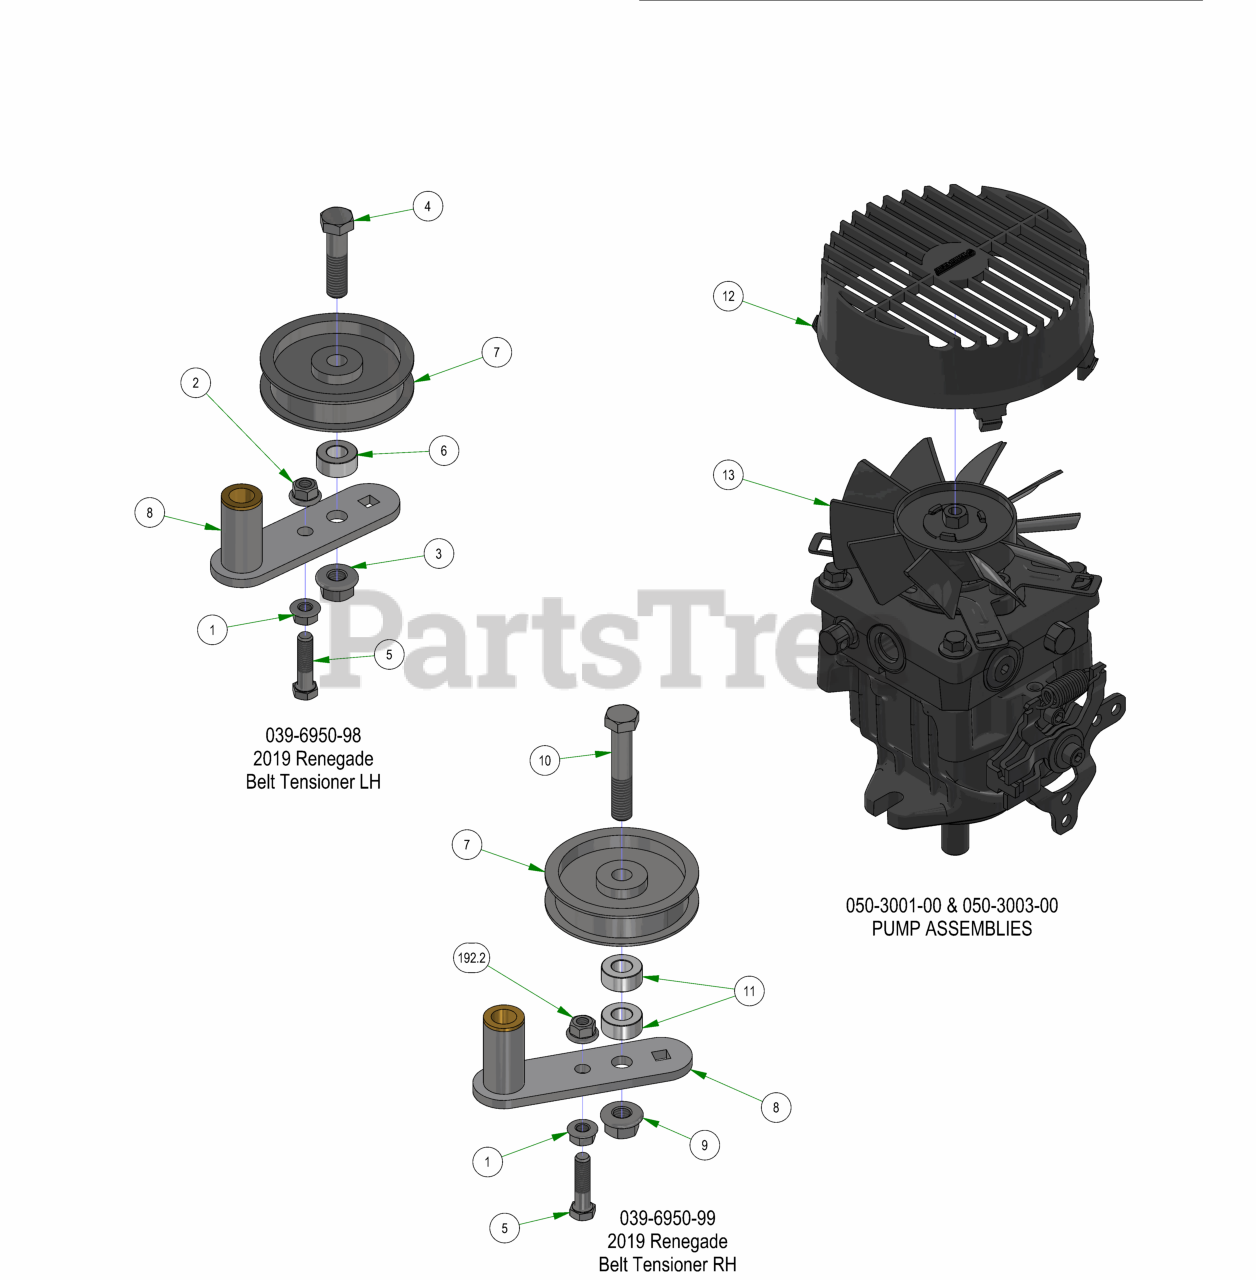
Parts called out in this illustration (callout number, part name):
1	3/8-16 HEX SERRATED FLANGE NUT HARD/ZINC
2	3/8-16 NYLON INSERT FLANGE LOCKNUT (GR.F) ZINC
3	1/2-13 NYLON INSERT FLANGE LOCKNUT ZINC
4	1/2-13 X 2 HEX CAP SCREW (GR.8) ZINC YELLOW
5	3/8-16 X 1-1/2 HEX CAP SCREW (GR.5) ZINC
6	1/2 Solid Shaft Collar (W/1 Set Screw) Zinc
7	3.25 Flat Idler Pulley
8	Horizontal Idler Arm with Bushings
9	1/2-13 NYLON INSERT FLANGE LOCKNUT ZINC
10	1/2-13 X 2-3/4 HEX CAP SCREW (GR.5) ZINC
11	1/2 Solid Shaft Collar (W/1 Set Screw) Zinc
12	Fan Guard 6" - Fits Wheel
13	Hydro Fan - Light/Pup/Outlaw XP
